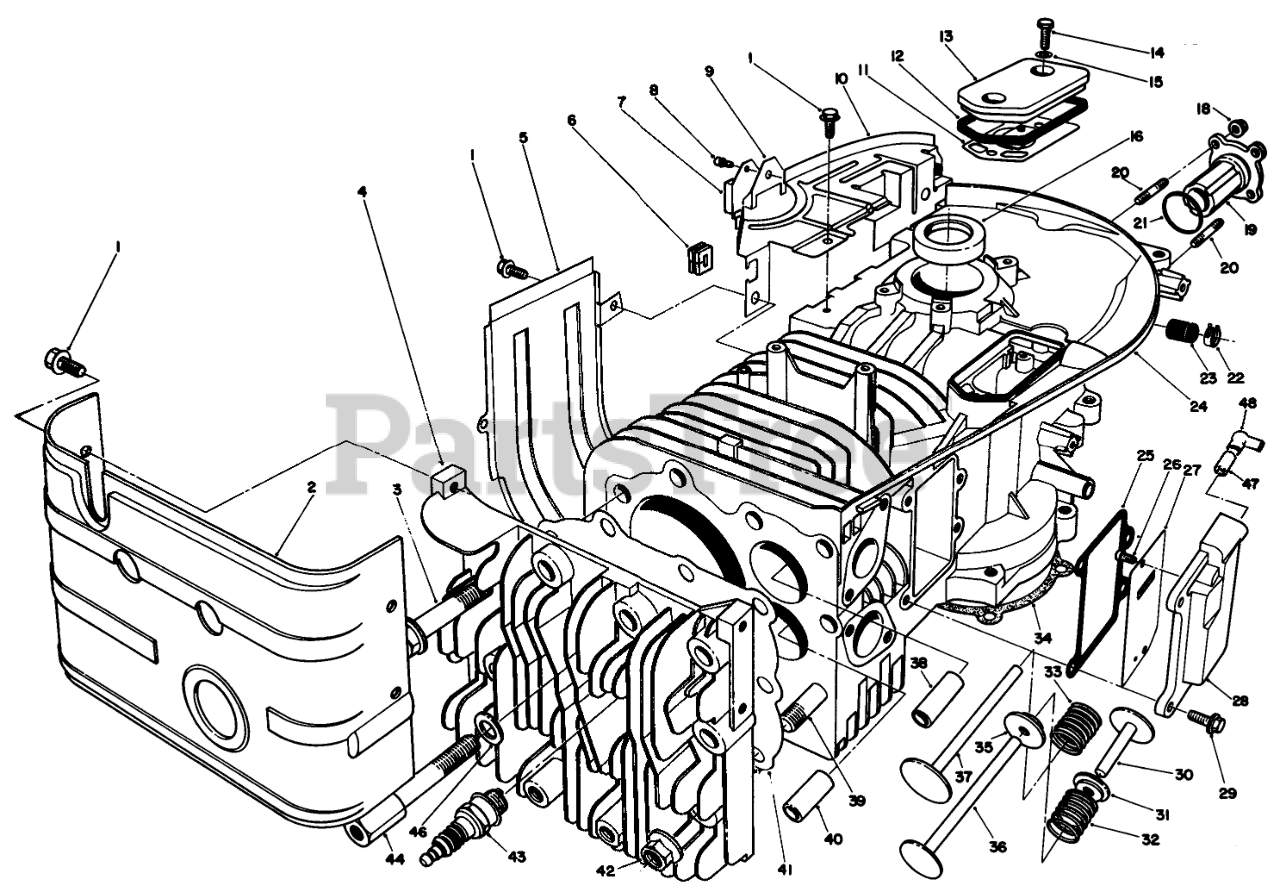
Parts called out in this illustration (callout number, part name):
1	Bolt-Flanged (6X10)
3	Bolt
4	Cylinder Head
7	Igniter
10	Fan Housing
14	Bolt
16	Seal-Oil
18	Nut
19	Shaft
24	Crankcase Assembly
28	Cover-Valve Chamber
29	Bolt-Flanged (6X16)
31	Retainer-Spring
32	Spring-Valve
33	Spring-Valve
34	Gasket
36	Exhaust Valve
37	Intake Valve
38	Guide-Intake Valve
40	Guide-Exhaust Valve
41	Gasket
43	Spark Plug
46	Washer
